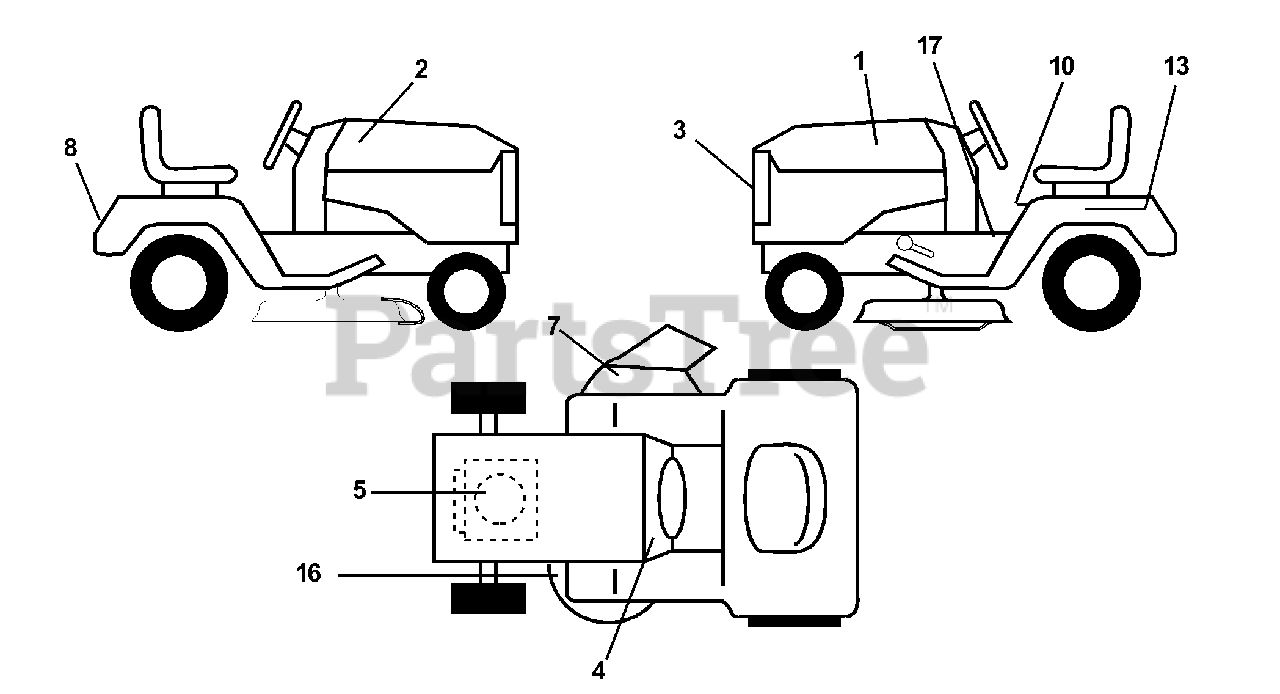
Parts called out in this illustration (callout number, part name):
1	Decal, Hood, L. H.
2	Decal, Hood, R. H.
3	Decal, Grille
4	Decal, Dash
5	Decal, Engine
7	Decal, Deck Warning
8	Decal, Logo, Fender
10	Decal Caution Fender
13	Decal, Caution, Battery
16	Decal, V-Belt Sch.
17	Decal, Inst. Oper.
